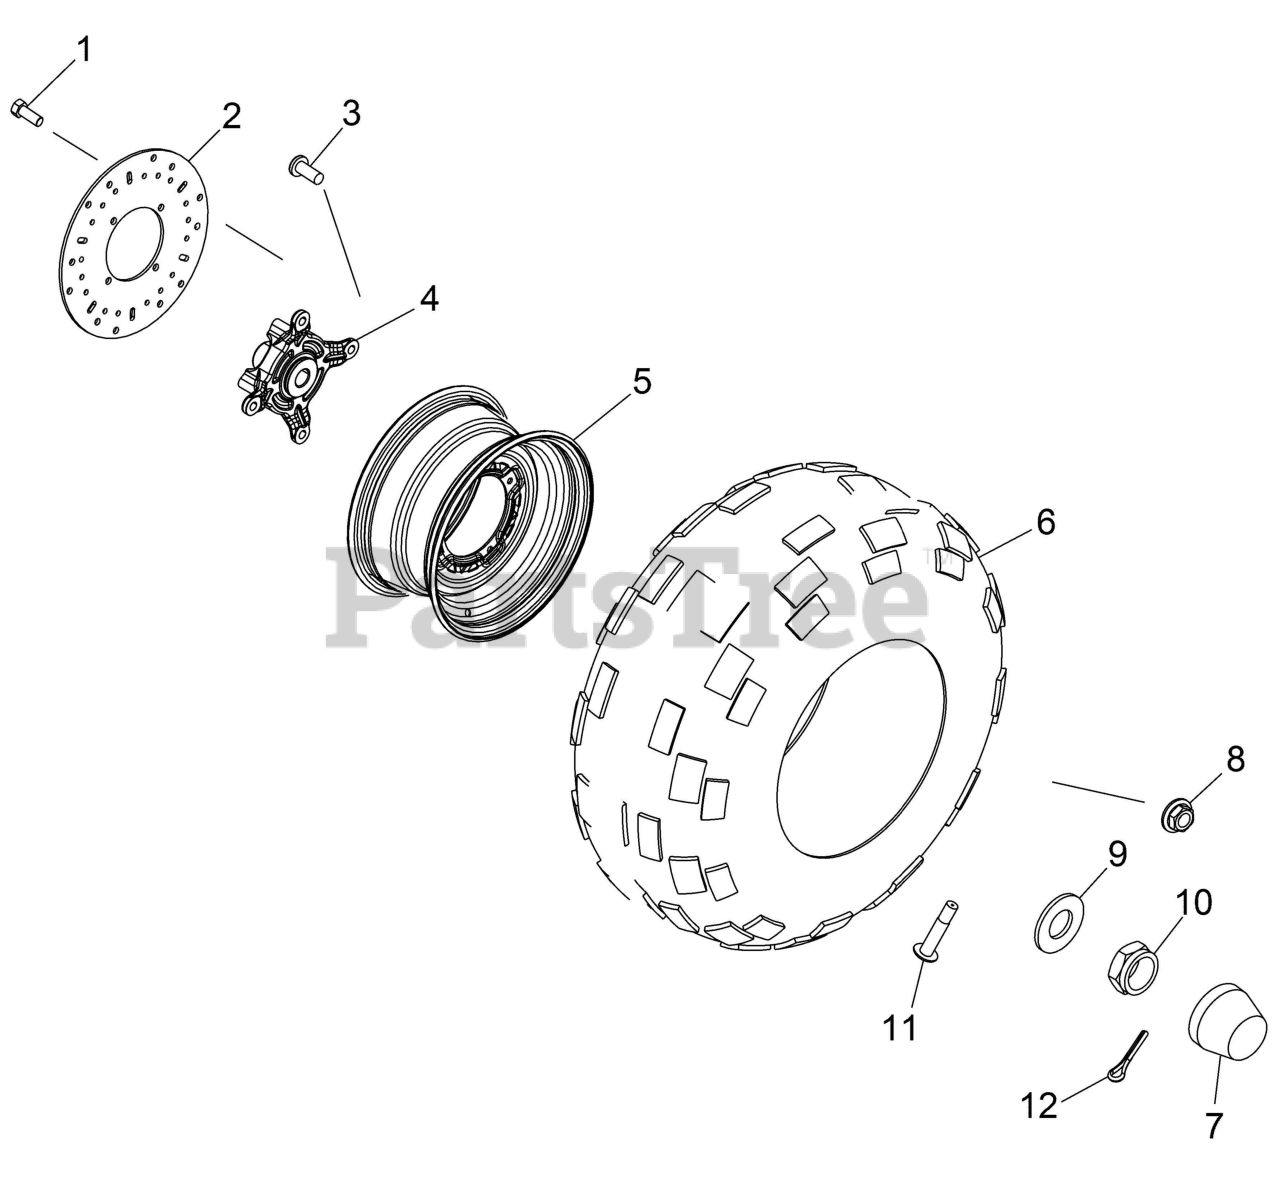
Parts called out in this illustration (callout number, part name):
1	SCR-M10X1.5X20 8.8 TXCS FL ZOD
2	DISC-BRAKE, FRONT
3	STUD-WHEEL,M12-1.5
4	HUB-WHEEL,FRONT(MACH),BLK
5	WELD-RIM,FR,10 GA,12X6,M.BLK
6	TIRE, FRONT, 25X10-12
7	HUB-DUST COVER,INTRNL LIP,BLNK
8	NUT-LUG,M12
9	WASHER, CONE
10	NUT-M18X1.5,CASTLE,ZINC/YELLOW
11	VALVE, RIM
12	PIN, COTTER
